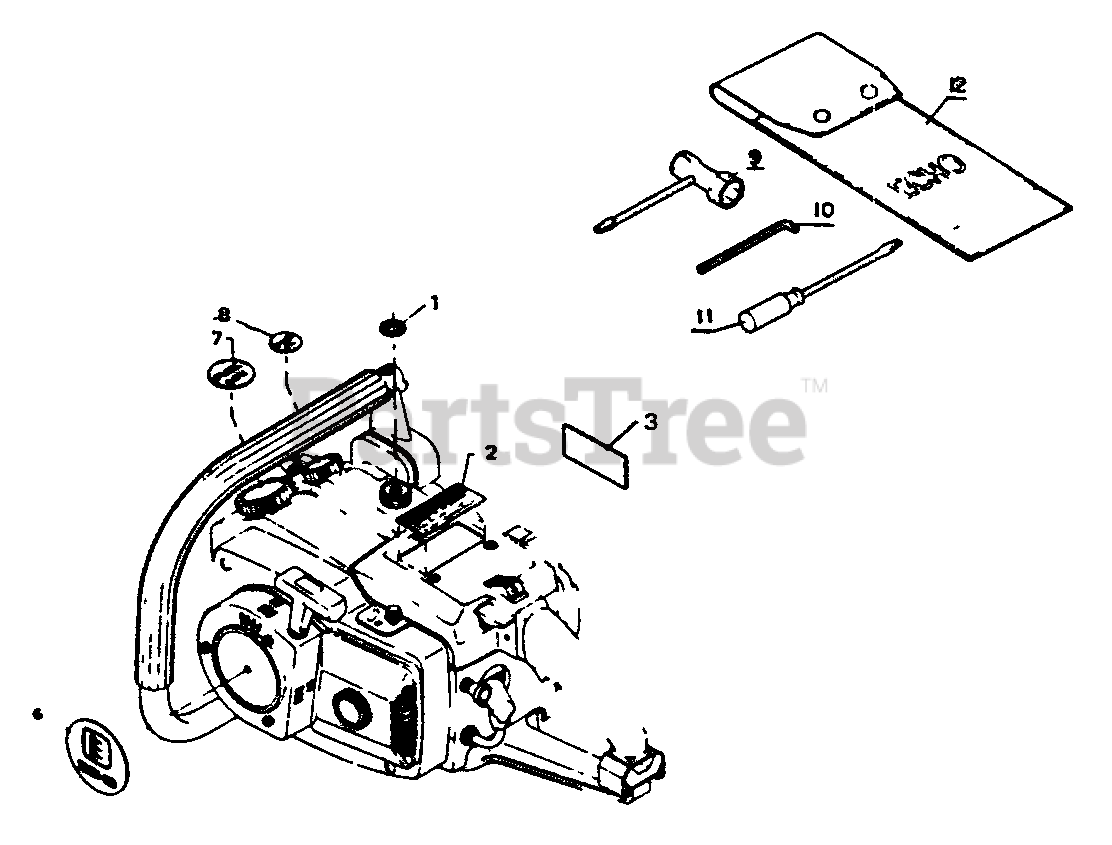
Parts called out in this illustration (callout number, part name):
1	LABEL - CAUTION
2	LABEL - CAUTION
3	LABEL - ECHO
6	LABEL - ECHO
7	LABEL - FUEL MIX
8	LABEL - CHAIN OIL
9	T-WRENCH - 13X19mm
10	HEX KEY - 4mm
11	SCREWDRIVER
12	BAG, TOOL
